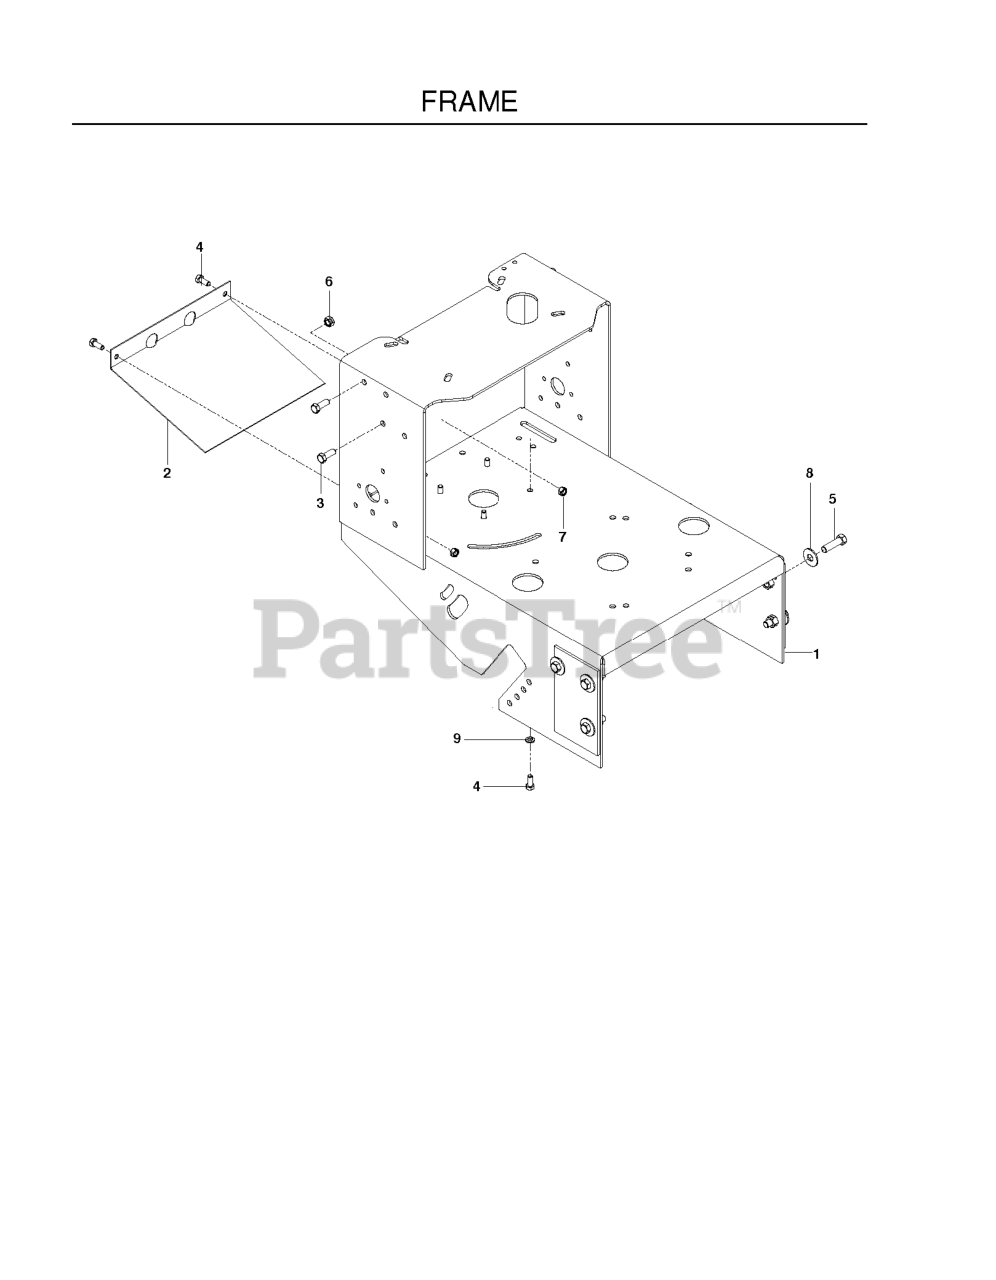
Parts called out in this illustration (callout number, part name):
1	WLDMT, REAR DECK, ORG
2	LOWER BELT SHIELD
3	HCS 3/8-16X1.GRD.5.ZD
4	HCS 5/16C X 3/4
5	HCS 7/16C X 1 1/2
6	NUT 3/8C CENTERBLOCK
7	NUT 5/16C CENTERLOCK
8	WASHER 7/16 FLAT ZD
9	WASHER.LOCK.HVY.HLCL.SPR.5/16
